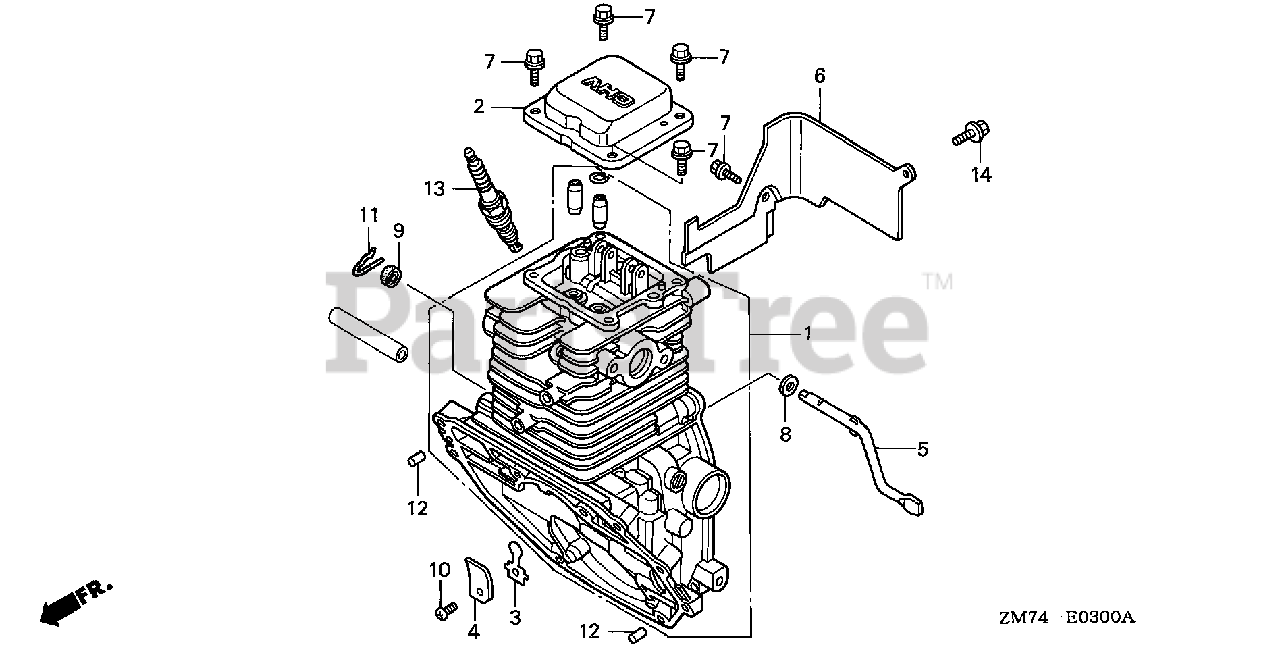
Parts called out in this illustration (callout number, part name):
1	CYLINDER
2	COVER, HEAD
3	VALVE, OIL OUTLET
4	PLATE, STOPPER
5	SHAFT, GOVERNOR ARM
6	SHROUD
7	BOLT, FLANGE (5X12)
8	WASHER (5.2X9)
9	OIL SEAL (5X11X5)
10	SCREW, PAN (3X5)
11	PIN, LOCK (6MM)
12	ROLLER (6X15)
13	SPARK PLUG (U14FSR-UB) (DENSO)
13	SPARK PLUG (CR4HSB)
13	SPARK PLUG (U16FSR-UB) (DENSO)
13	SPARK PLUG (CR5HSB)
14	BOLT, FLANGE (5X12)
